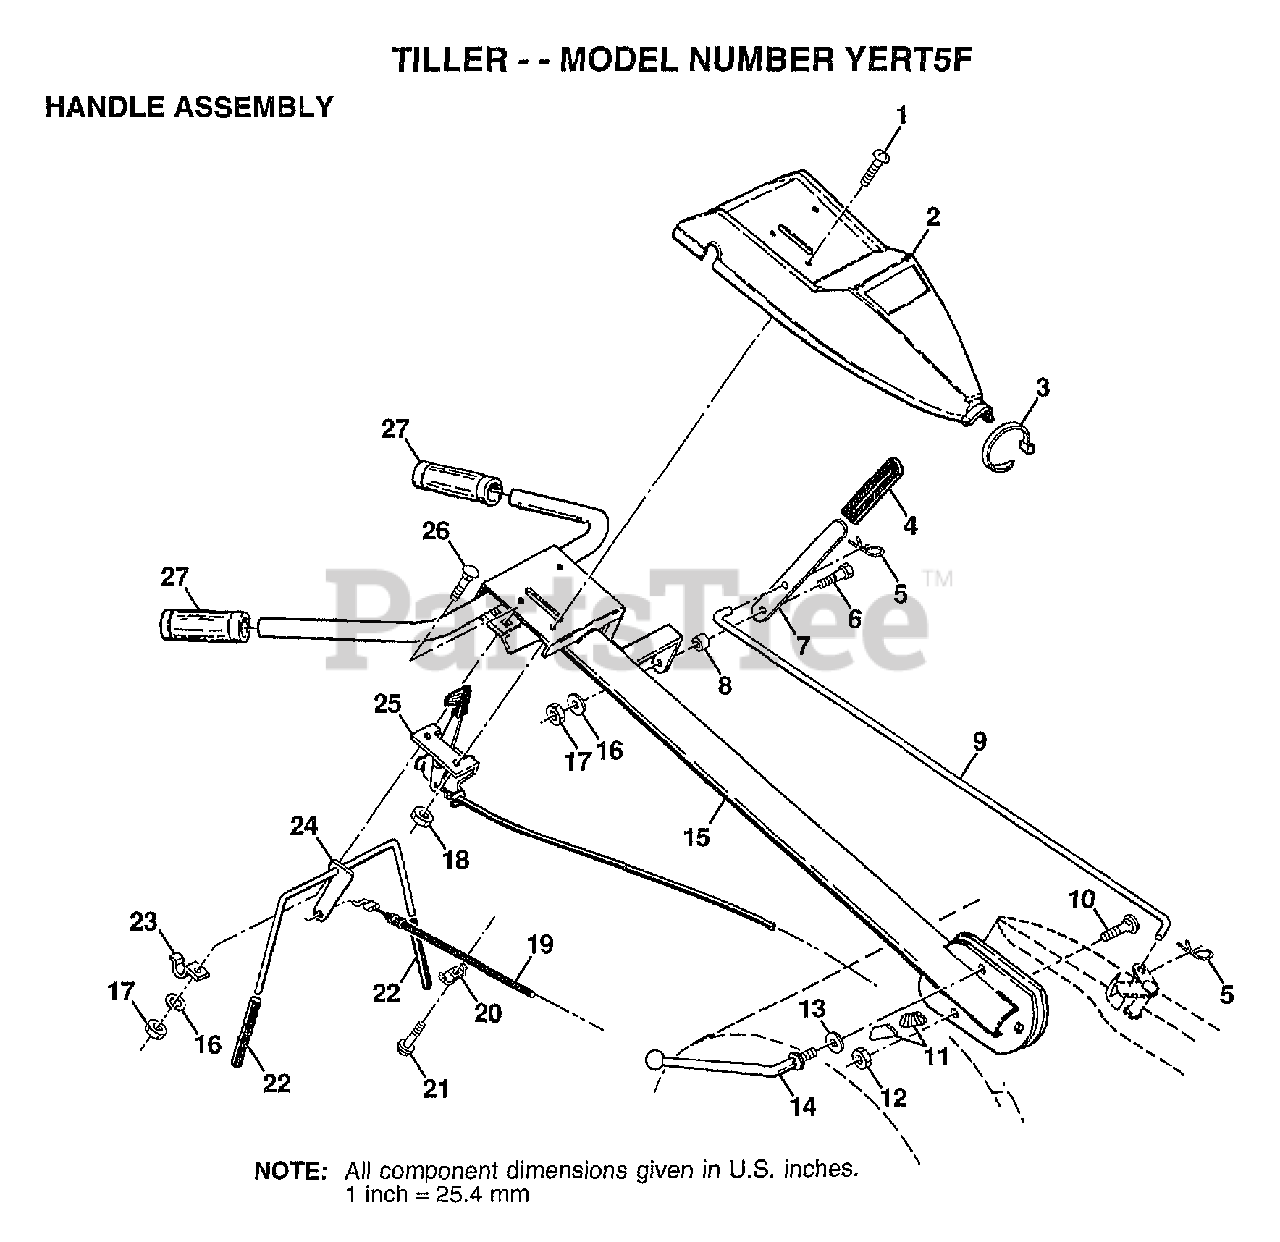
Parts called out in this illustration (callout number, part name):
1	SCREW.PNHD.10-24
2	"PANEL,CONT TI"
3	TIE CABLE CRT
4	GRIP T
5	RETAINER M
6	SHOULDER BOLT ST
7	SHIFT HANDLE CRT
8	GROMMET CRT
9	SHIFT ROD CRT
10	BOLT D
11	LOCK CRT
12	LOCKNUT
13	WASHER CRT
14	LEVER LOCK CRT
16	LOCKWASHER
19	CABLE.CLUTCH.48.Z
20	CONDIUT CLIP T
22	GRIP BAR CRT
24	"ASSY CONTROL, BAR"
25	"CONT,THROTTLE"
26	BOLT
27	GRIP NUB SNGL HDL
